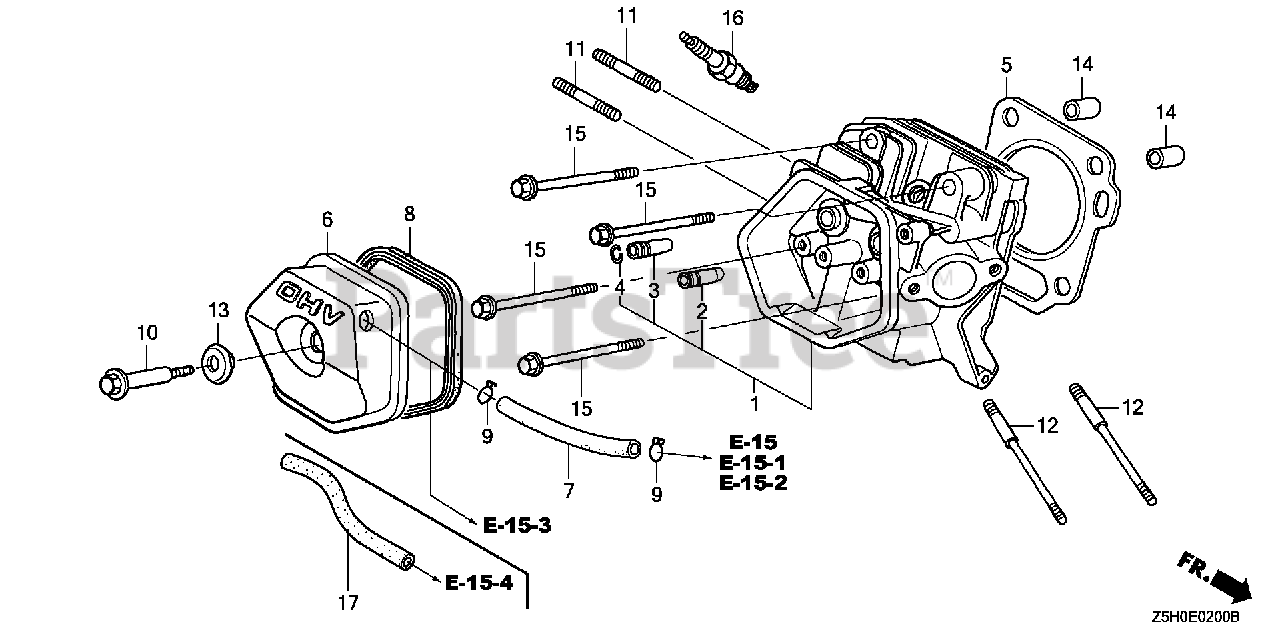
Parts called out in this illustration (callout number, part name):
1	CYLINDER HEAD
2	GUIDE, VALVE (OVER SIZE)
3	GUIDE, EX. VALVE (OVER SIZE)
4	CLIP, VALVE GUIDE
5	GASKET, CYLINDER HEAD
6	COVER, HEAD
7	BULK HOSE, VACUUM (11X1000) (11X100)
8	GASKET, HEAD COVER
10	BOLT, HEAD COVER
11	BOLT, STUD (8X32)
12	BOLT, STUD (8X123)
13	WASHER, HEAD COVER
14	PIN, DOWEL (12X20)
15	BOLT, FLANGE (10X80)
16	SPARK PLUG (BPR5ES) (NGK)
16	SPARK PLUG (W16EPR-U) (DENSO)
16	SPARK PLUG (BPR6ES) (NGK)
16	SPARK PLUG (W20EPR-U) (DENSO)
